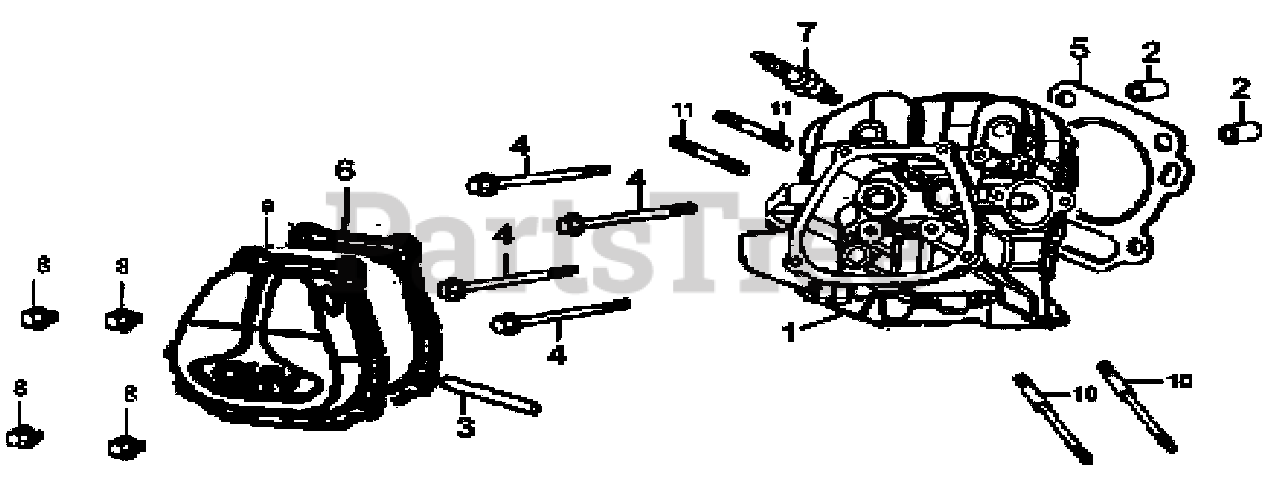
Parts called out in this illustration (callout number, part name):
1	HEAD, CYLINDER
2	PIN, DOWEL
3	TUBE, BREATHER
4	BOLT, FLANGE
5	GASKET, CYLINDER
6	GASKET, HEAD COVER
7	PLUG, SPARK
8	BOLT, FLANGE
9	COVER, HEAD
10	BOLT, STUD, INTAKE
11	BOLT, STUD, EXHAUST
